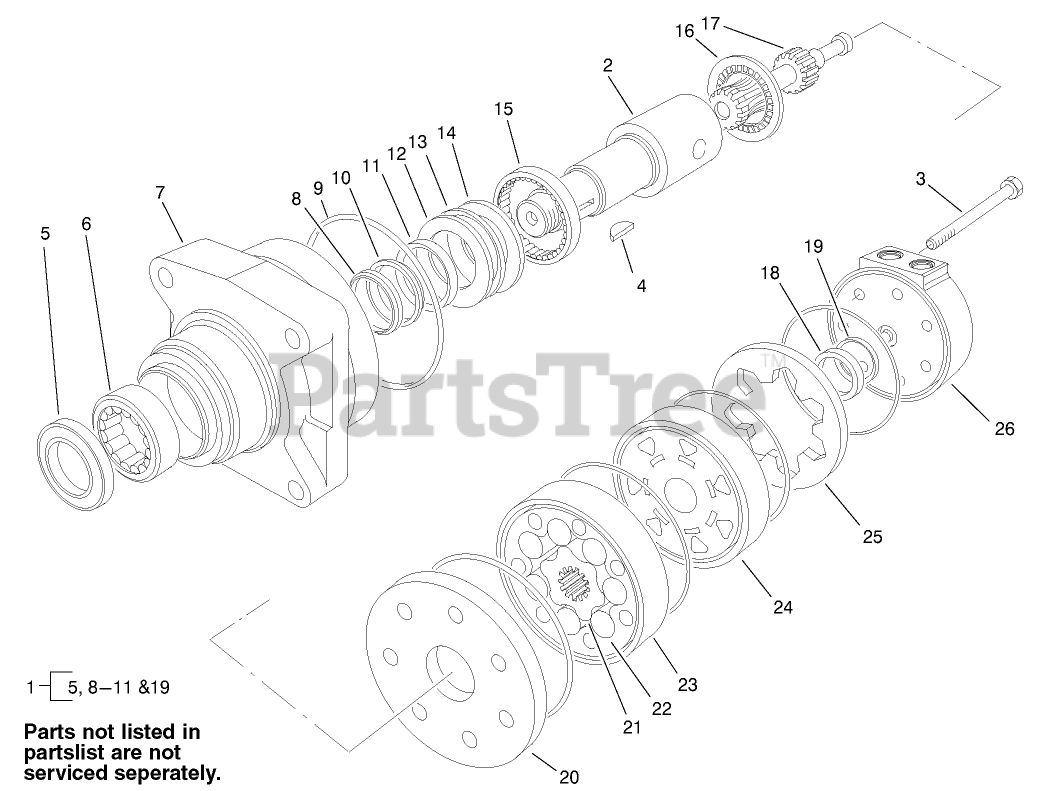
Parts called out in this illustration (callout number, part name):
1	SEAL KIT
2	SHAFT-COUPLING
3	SCREW-HH
4	KEY-WOODRUFF
